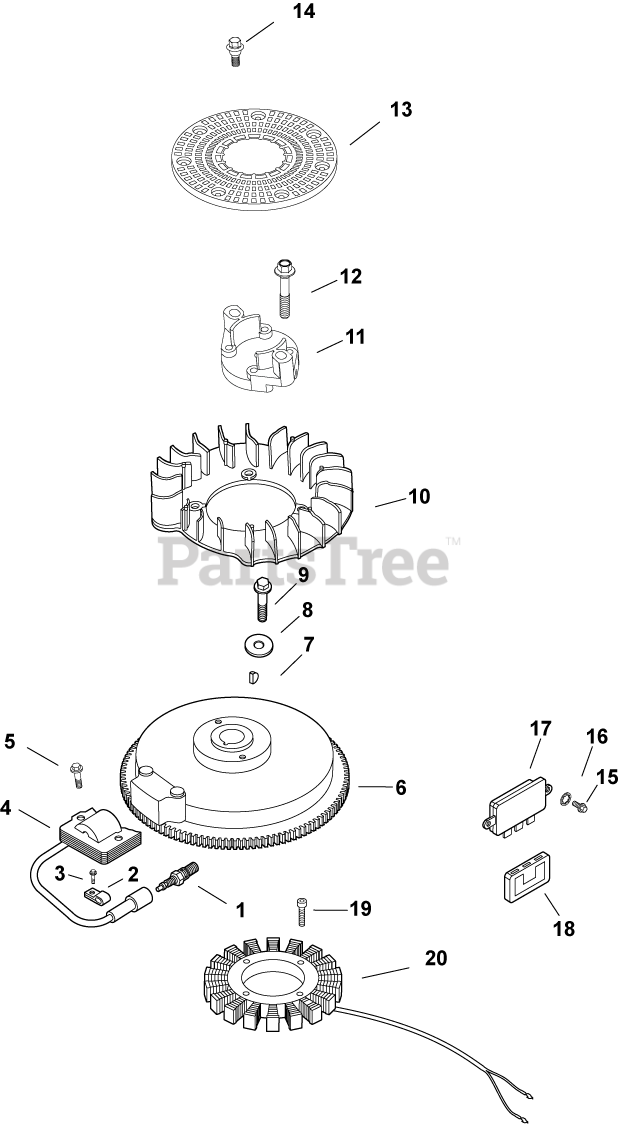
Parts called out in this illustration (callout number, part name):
1	PLUG, SPARK (STD)
2	SCREW, FLG THD FRM M5X.8X10
4	MODULE, IGNITION
5	SCREW, FLG THD FRM M5X.8X20-(#25086399S)
7	KEY, 3/16" X 5/8"
8	WASHER, FLAT 13/32"
9	SCREW, FLG M10X1.5X45 - (#25086361S)
10	FAN - DISCONTINUED
11	ADAPTER, DRIVE SHAFT
12	SCREW, HEX FLANGE -USE 24 086 17-S
13	SCREEN, GRASS
14	BOLT, SHOULDER
15	SCREW, FLG M6X1.0X16
16	WASHER, INT TOOTH LOCK 1/4"
17	REG/RECT-15 AMP (KM)-USE 41 403 10-S
18	CONNECTOR, BODY (KM)-USE 25 155 41-S
19	SCREW, M5X0.8X25 - (#25086402S)
20	KIT, 15 / 20 AMP STATOR
